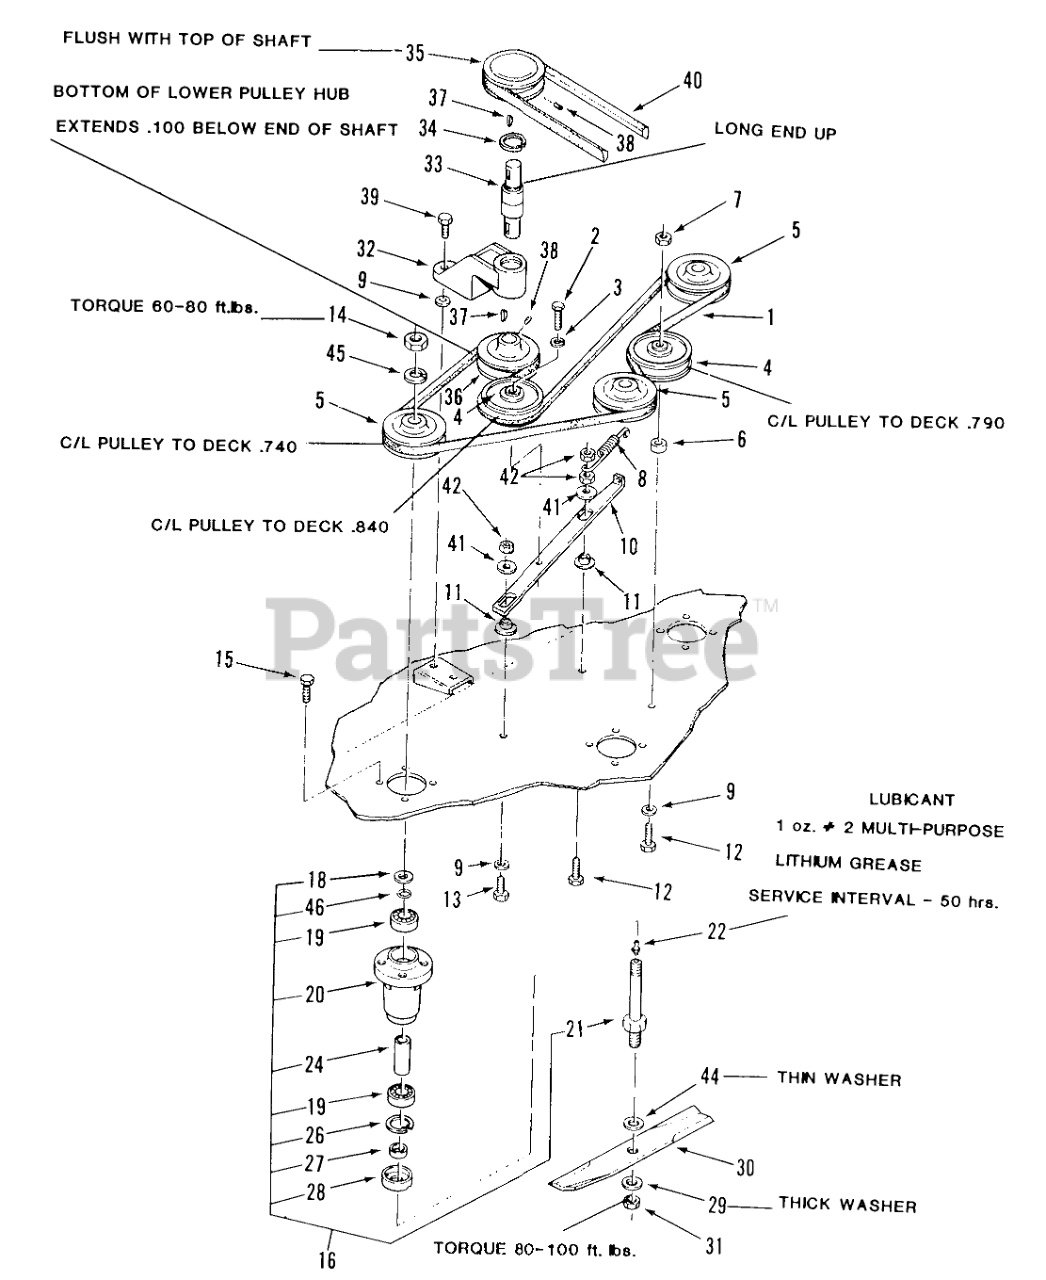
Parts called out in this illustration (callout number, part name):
1	BELT-V
2	BOLT HEX SPECIAL
3	LOCKWASHER
4	Idler Pulley
5	PULLEY
6	SPACER
7	Nut
8	SPRING-EXTENSION
9	WASHER
10	BAR-IDLER SUPPORT
11	SPACER-BUSHING
12	Bolt
13	Bolt
14	X-REF 3220-6
15	Bolt
16	ASSY 36" SPINDLE
18	Washer
19	BEARING-BALL
20	HOUSING-SPINDLE
21	Spindle Shaft
22	Zerk
24	Spacer
26	Ring-Snap
27	SPACER-BLADE
28	CUP-SPINDLE
29	SpeciaI Washer
30	S/A BLADE KIT
31	X-REF 3220-7
32	HOUSING DRIVE BRG R
33	BRG INTEGRAL SHAFT
34	Snap Ring
35	PULLEY
36	PULLEY-LOWER
37	KEY-WOODRUFF
38	Set Screw
39	Bolt
40	V-BELT
41	WASHER
42	NUT
44	Washer
45	Lockwasher
46	O RING
